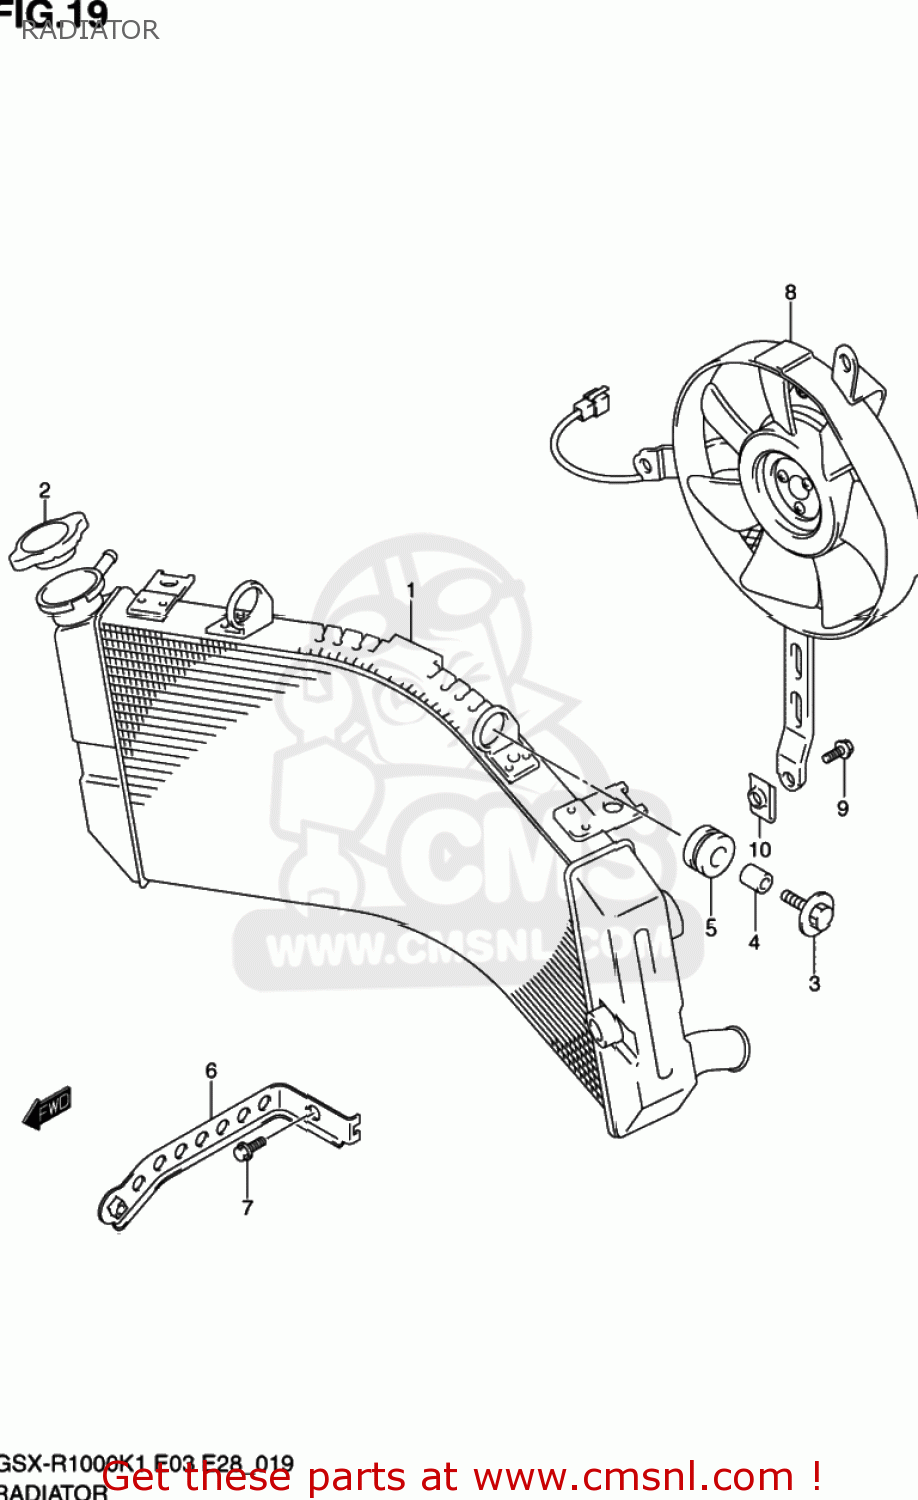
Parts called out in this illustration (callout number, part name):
1	RADIATOR ASSY,
2	CAP COMP,RADIATOR
3	BOLT(6X25)
4	SPACER(6.5X10X12)
5	CUSHION
6	BRACKET,RADIATOR
7	BOLT
8	FAN ASSY,RADIATOR,R
9	BOLT
10	NUT
